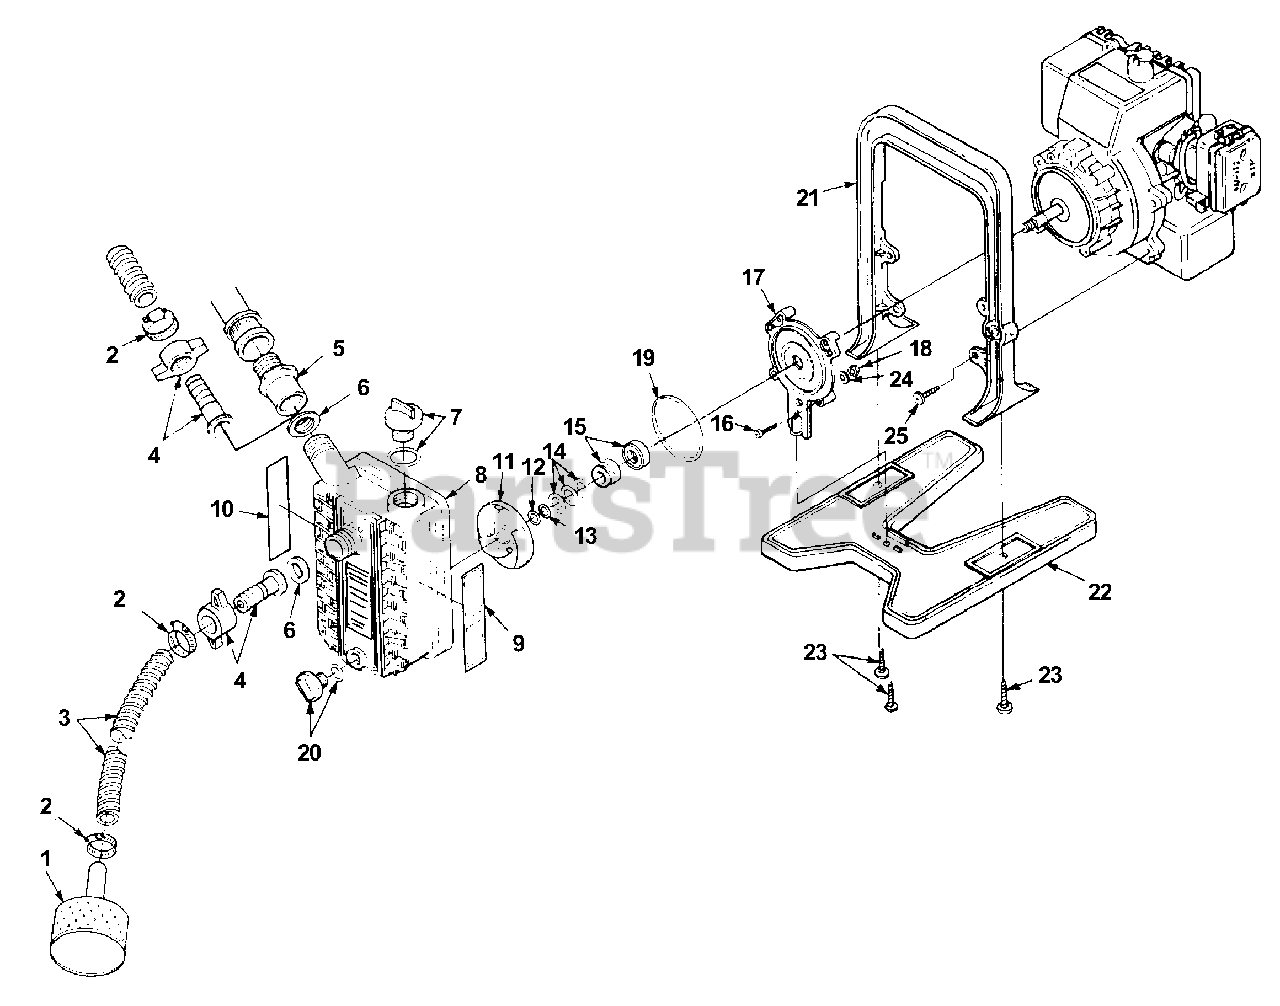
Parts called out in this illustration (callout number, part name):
1	STRAINER (1")
3	HOSE (1")
4	BARBED COUPLING
5	ADAPTOR-Garden Hose
7	CAP w/O-RING
8	PUMP BODY & DECALS
9	DECAL-Operation
10	DECAL-Warning
11	IMPELLER
12	SHIM-(.030")(Impeller)
13	SHIM-(.015")(Impeller)
14	SHIM-(.030")(Seal)
16	SCREW-Pan Hd. (10-24 X 1")
17	ADAPTER (Engine to Pump)
18	NUT (M5)
19	O-RING
20	CAP w/O-RING
21	HANDLE-Engine Mtg.
22	BASE PLATE
23	SCREW-Thread Form. (10-14 X 3/4")
24	WASHER-Flat(M5)
25	SCREW-Thread Form. (10-24 X 1")
